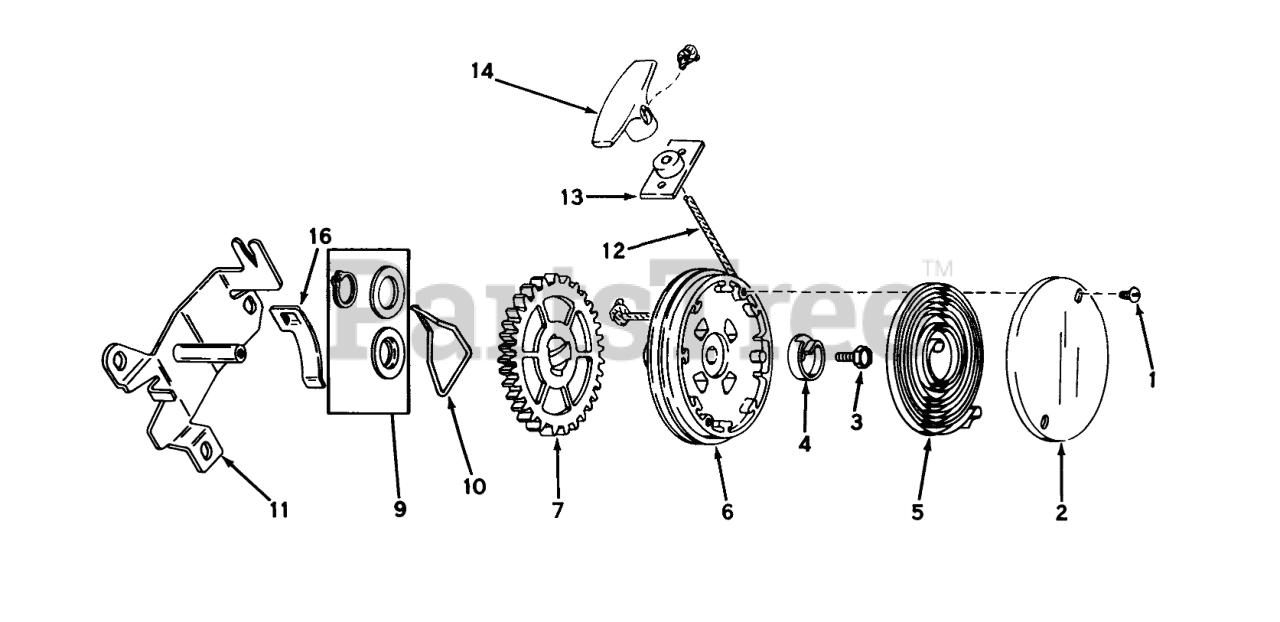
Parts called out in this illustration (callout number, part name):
2	Cover, Spring
3	Screw, Hex Washer Head
4	Hub Spring
5	Spring, Rewind
6	Pulley Assy. (Incl. Ref. #9)
9	Kit, Thrust Wash. & Snap Rg.
11	Bracket Assy. Mounting
12	Rope-Starter
13	Bracket Assy.
14	Handle-Starter
16	Clip Rope
